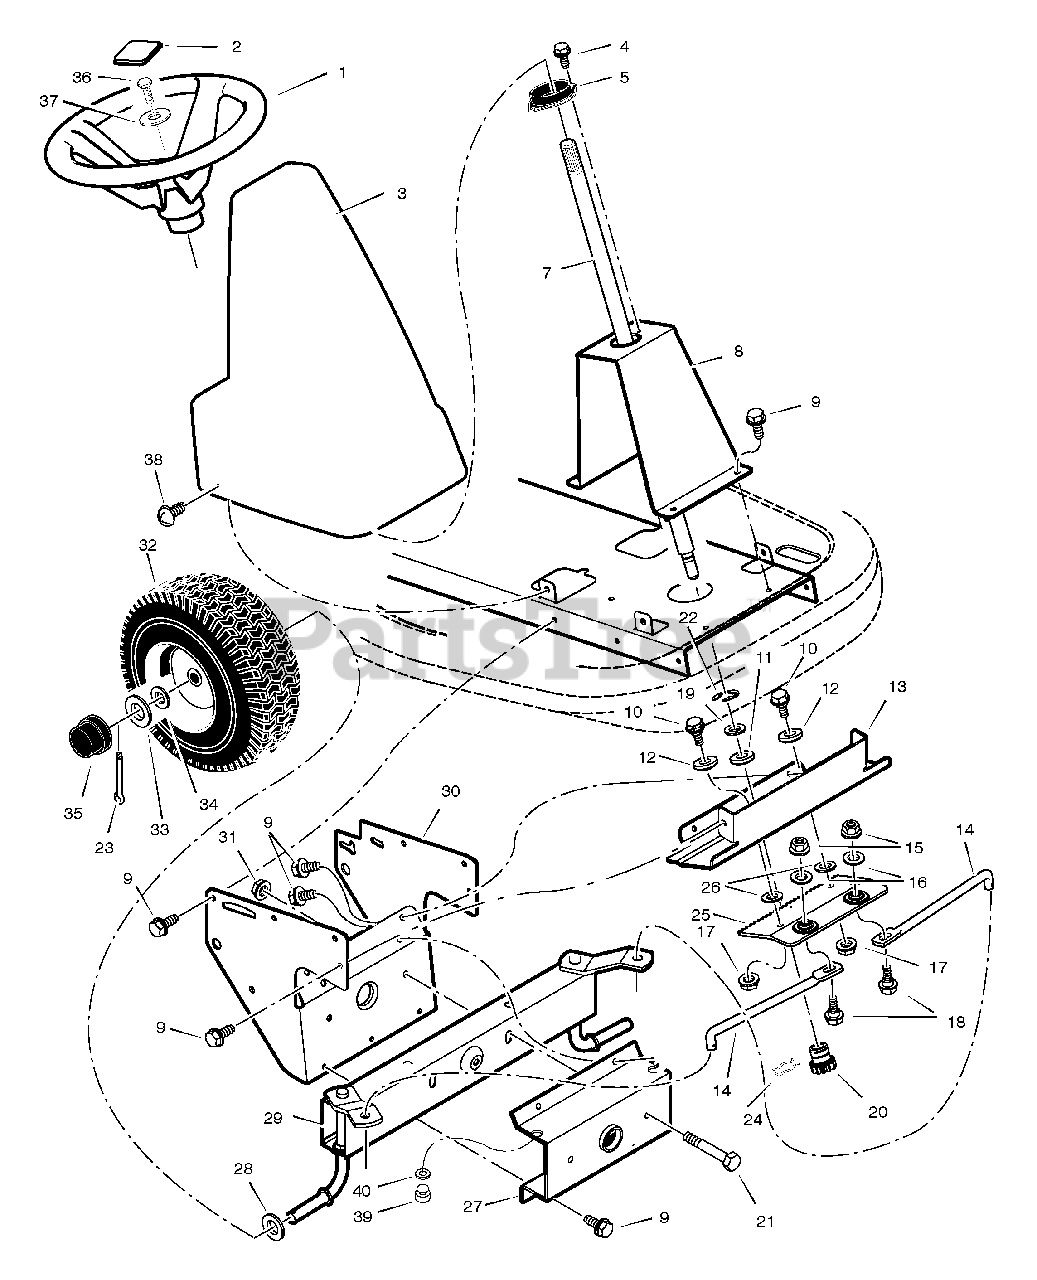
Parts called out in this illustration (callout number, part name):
1	Wheel, Steering
2	Cap, Steering (Black)
3	Console, High (Black)
4	Screw
5	Bearing, Upper Steering
7	Shaft, Steering
8	Support, Steering
10	Bolt, Shoulder
11	Bearing, Lower Steering
13	Plate, Gear Mounting
14	Link, Drag
15	Nut, Flange
16	Washer
17	Nut, Flange
18	Bolt, Hex
19	WASHER, 1-1.3 16G FLT
20	Gear, Pinion
21	Bolt, Hex
22	E-Ring, Retainer
23	Pin, Cotter
24	Retainer, Spring
25	Rack, Steering
27	Bracket, Axle Front
28	Washer
29	Axle & Spindle Assembly
30	Bracket, Support
31	Nut, Flange
32	Wheel, Front
34	Washer
35	Cap, Hub
36	Screw, Hex
37	Washer
38	Screw
39	Bumper, Rubber
